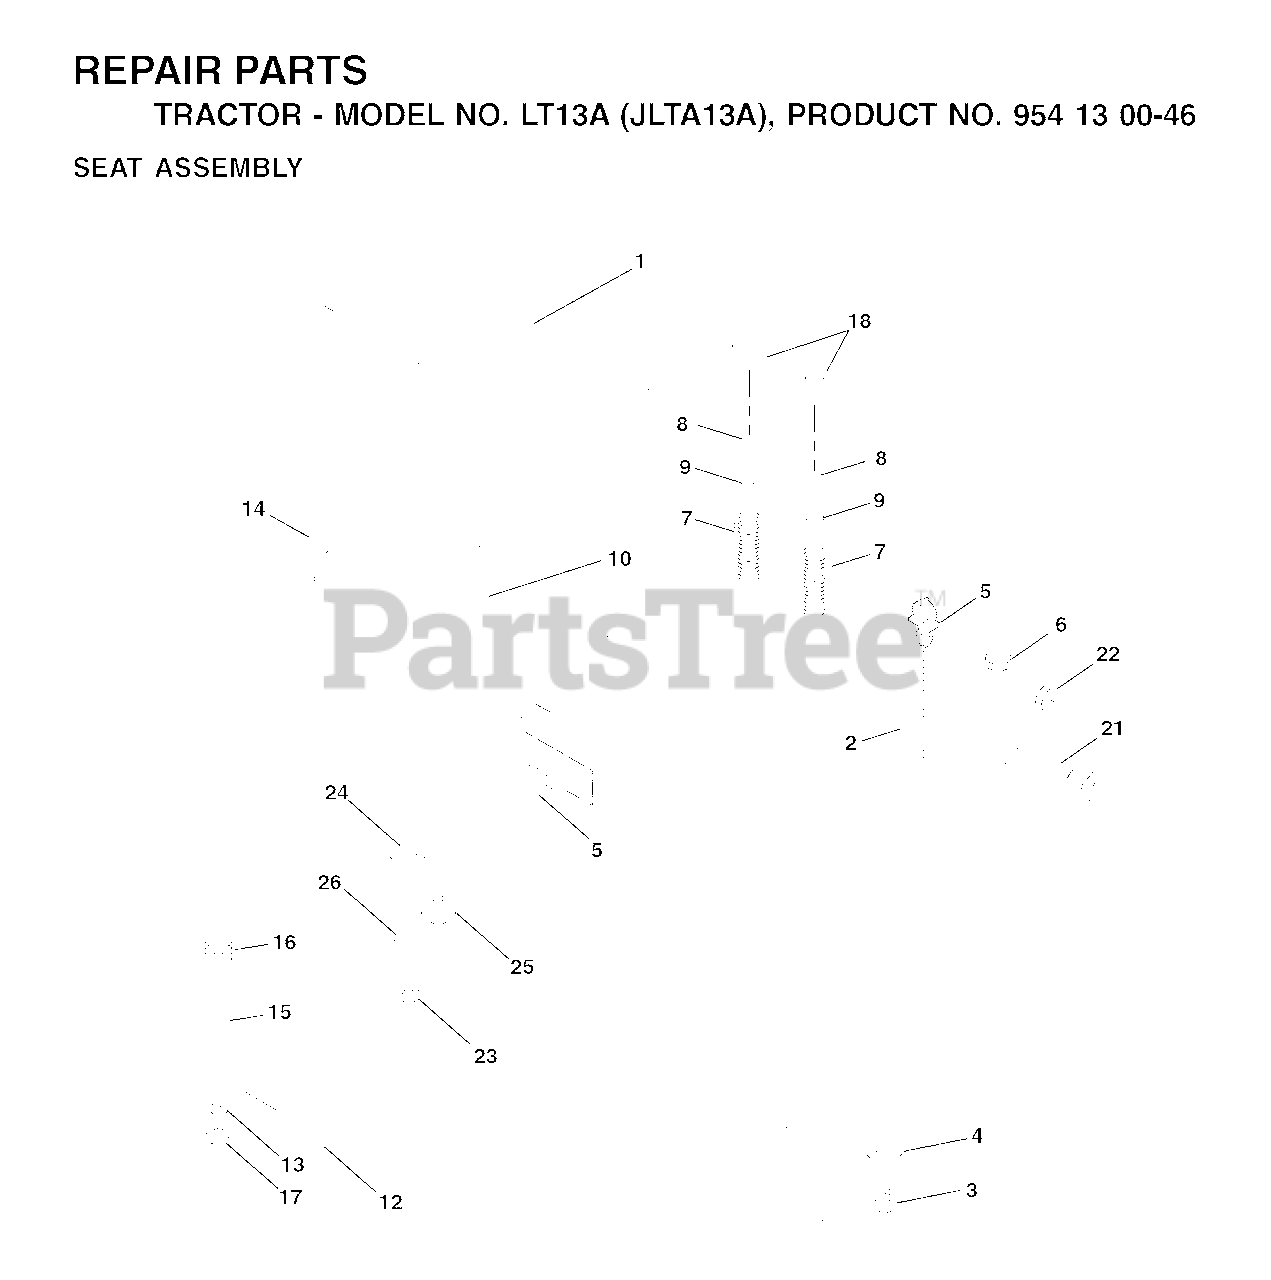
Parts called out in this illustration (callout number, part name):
2	SEAT PIVOT BRKT
4	WASHER PM
5	PUSH CLIP
6	NUT
7	SPRING COMPRESSION
8	SCREW 3/8-16X1
9	WASHER
10	PAN, SEAT
12	BRKT SWITCH
14	BOLT.ROUND.HEAD.SQUARE.NECK
15	SPACER SPLIT 28X.96
17	NUT T
18	CAP SPRING
21	BOLT.SHOULDER.5/16-18
22	NUT.71038.31-18.HEX.NYLOCK
23	BOLT.HEX.BLACK
25	BOLT,SHOULD
26	LOCKWASHER
